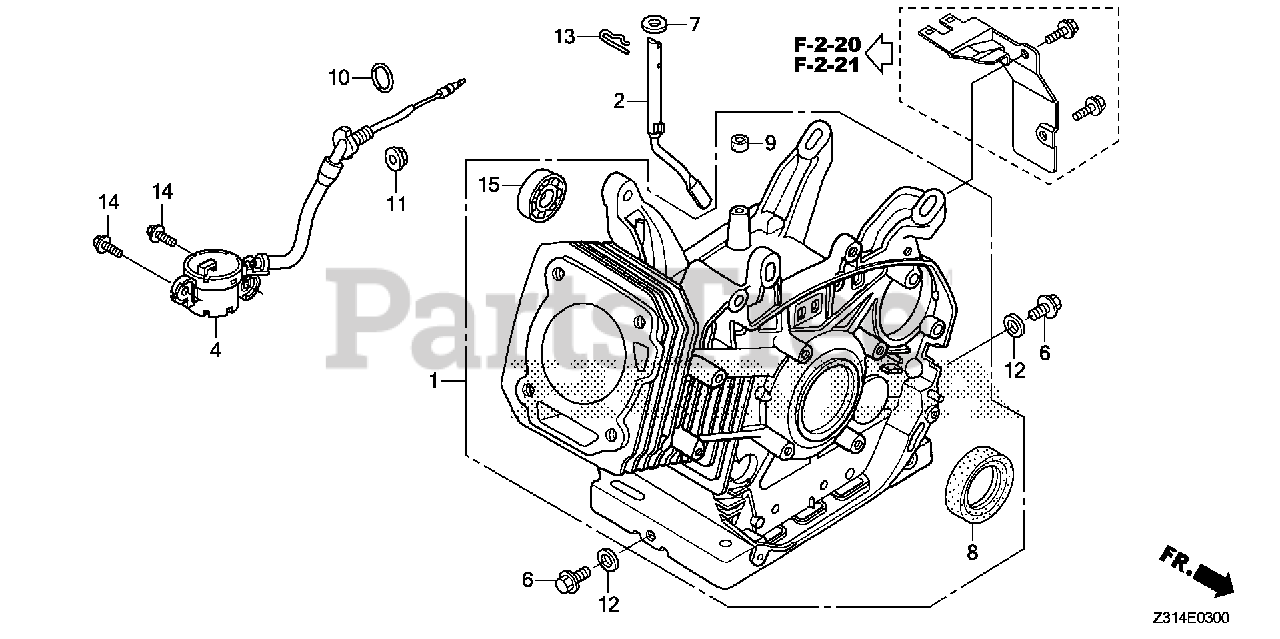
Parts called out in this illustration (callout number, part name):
1	CYLINDER ASSY. (ALERT)
2	SHAFT, GOVERNOR ARM
4	SWITCH ASSY., OIL LEVEL
6	BOLT, DRAIN PLUG
7	WASHER (8.2X17X0.8)
8	OIL SEAL (35X52X8) (NOK)
8	OIL SEAL (35X52X8)
9	OIL SEAL (8X14X5)
10	O-RING (14MM) (ARAI) Use up to Engine SN 2949254.
10	O-RING (14MM) (NOK)
11	NUT, FLANGE (10MM)
12	WASHER, DRAIN PLUG (12MM)
13	PIN, LOCK (10MM)
14	BOLT, FLANGE (6X12) Use up to Engine SN 1543277.
15	BEARING, RADIAL BALL (6202)
